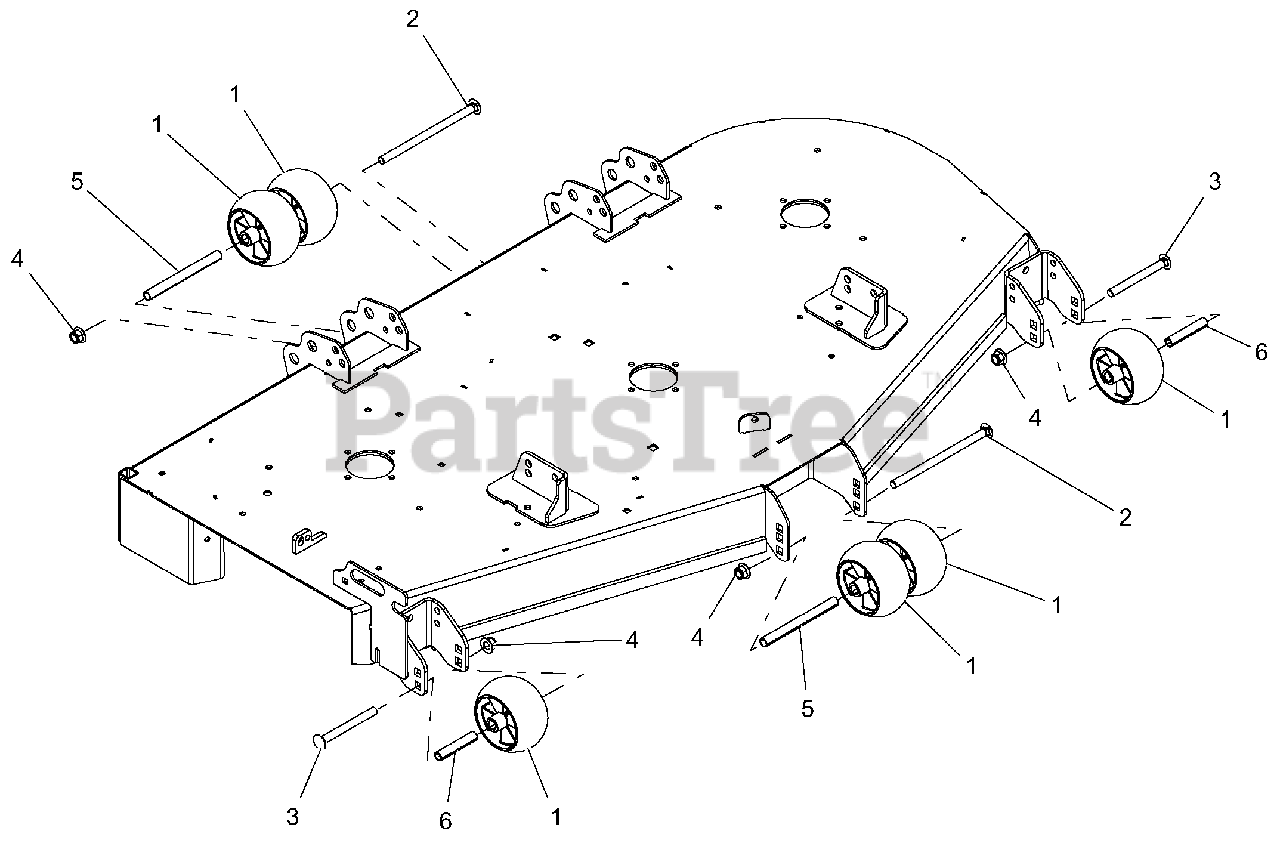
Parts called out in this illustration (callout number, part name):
1	ANTI-SCALP WHEEL - 5X3 CTR
2	BLT-RDHDSQNK .50-13X8.50 Y
3	BLT-RDHDSQNK .50-13X5.00 G5 YWZC
4	NUT-LK-NYL-FLG .50-13 YWZC
5	SPACER, .510X.625X6.70
6	SPACER, .510X.625X3.35
